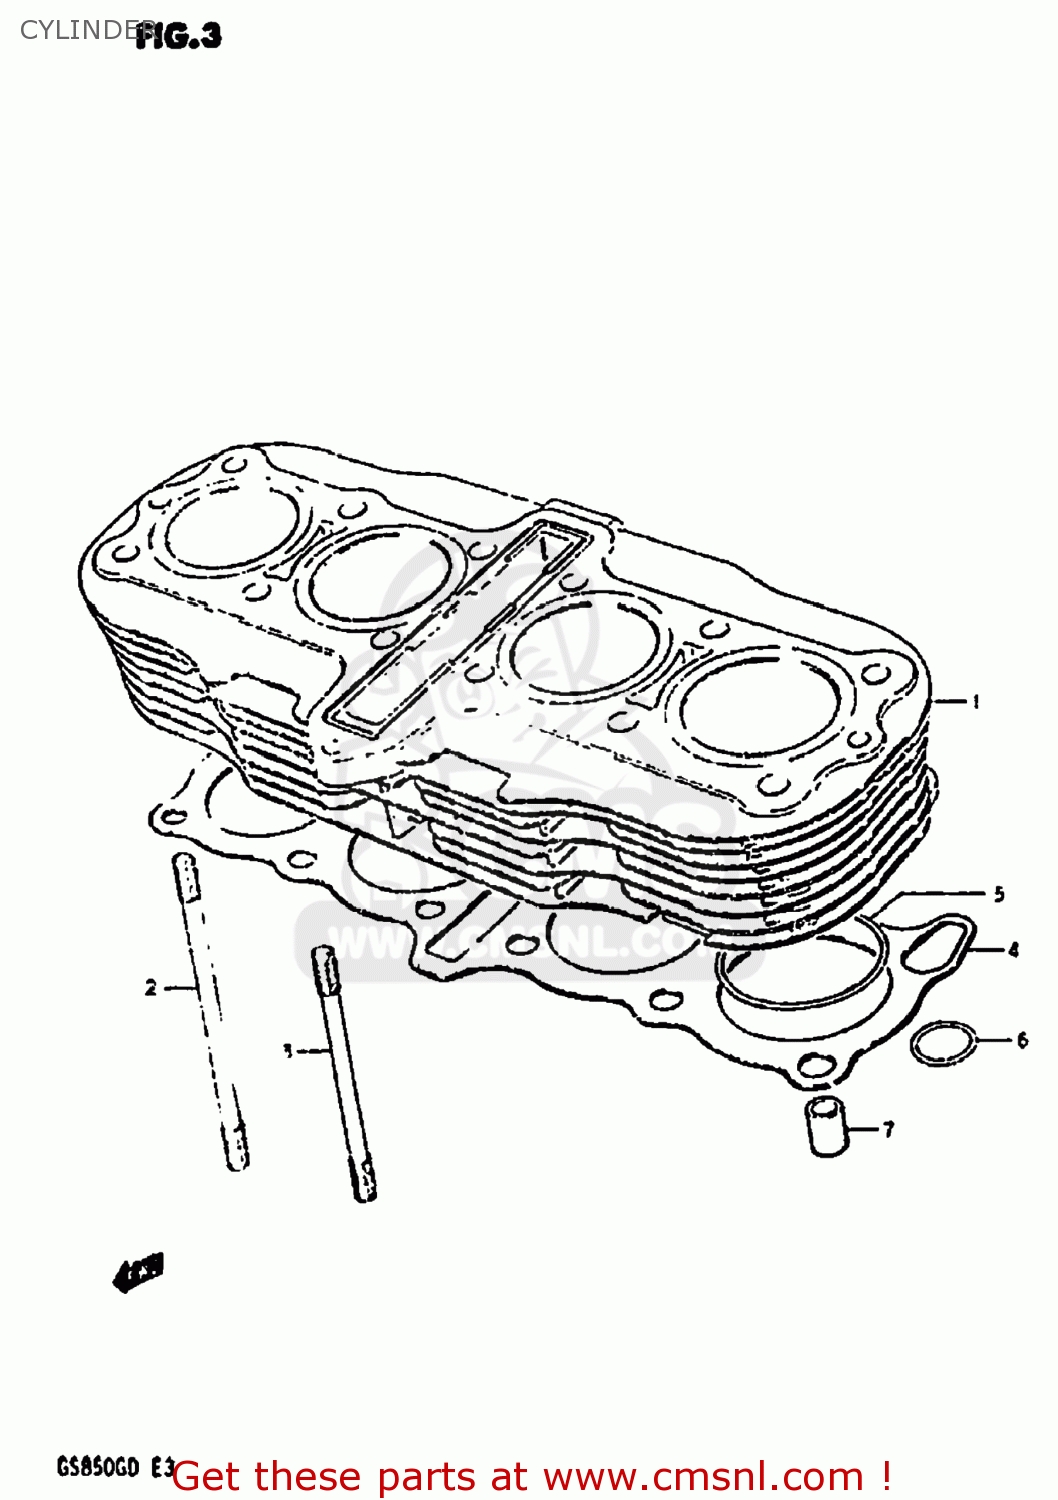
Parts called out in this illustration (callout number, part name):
1	CYLINDER
2	BOLT,STUD
3	STUD
4	GASKET,CYLINDER (MCA)
5	O RING(D:2,ID:70)
6	O RING(D:3.05)
7	PIN
